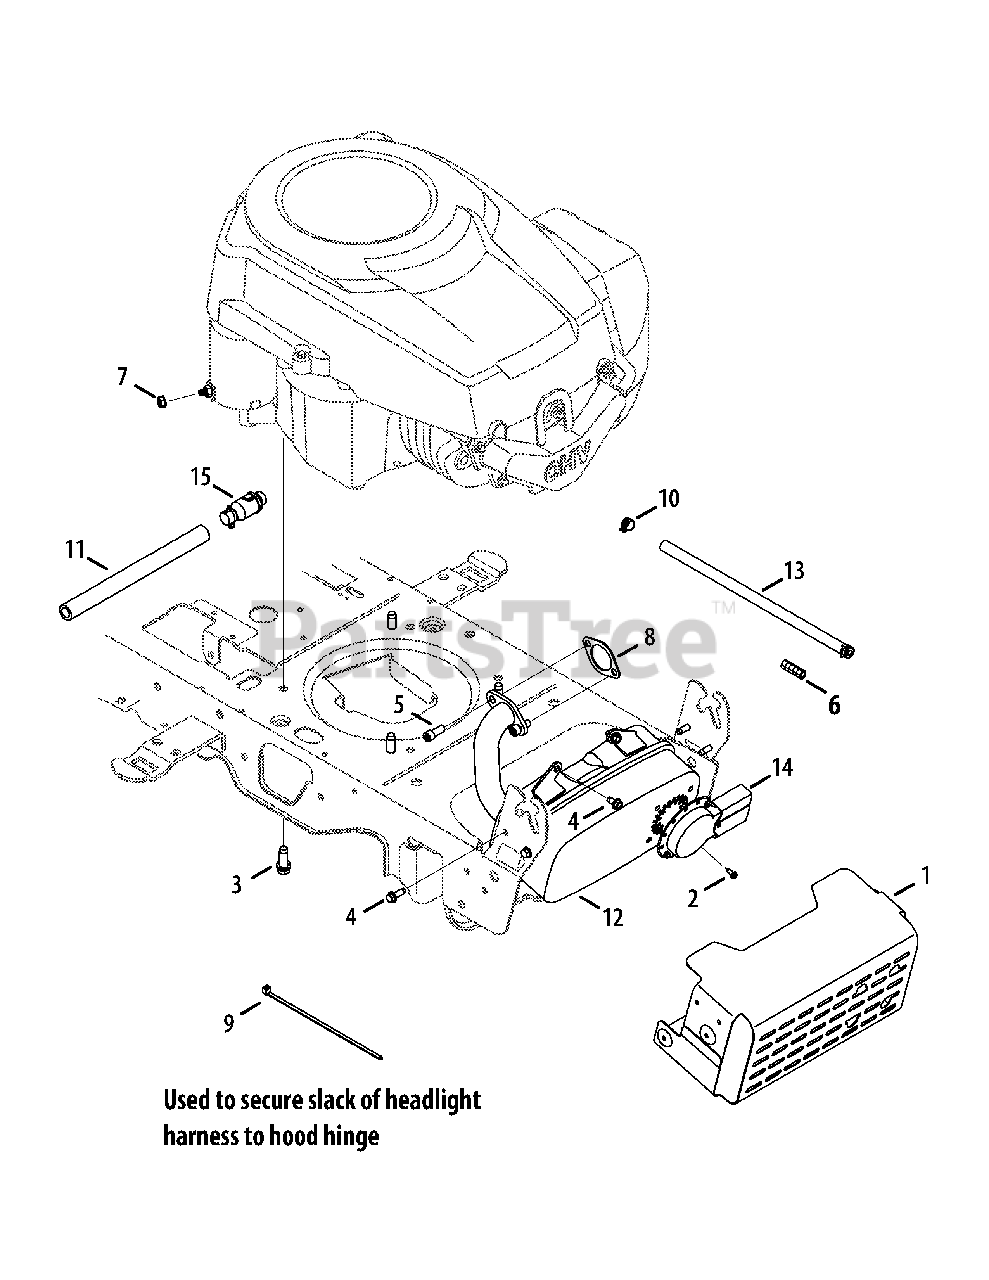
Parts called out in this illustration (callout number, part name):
1	Shield Ass’y, Muffler
2	Screw, Ab, #8-18, 0.500,
3	Screw, Self-tapping, 3/8-16, 1.000,
4	Screw, Self-tapping, 1/4-20, 0.500,
5	Screw, Socket Head, 5/16-18, .750
7	Nut, Sems, 1/4-20
8	Gasket, Exhaust
9	Cable, Tie, 3/16 x .05 x 7.4
10	Clamp, Hose, .490 Dia.
11	Hose, Extension, Oil Drain
12	Muffler, Single, Kohler
13	Hose, Fuel, Low Permeation, 1/4
14	Deflector, Muffler, Long
